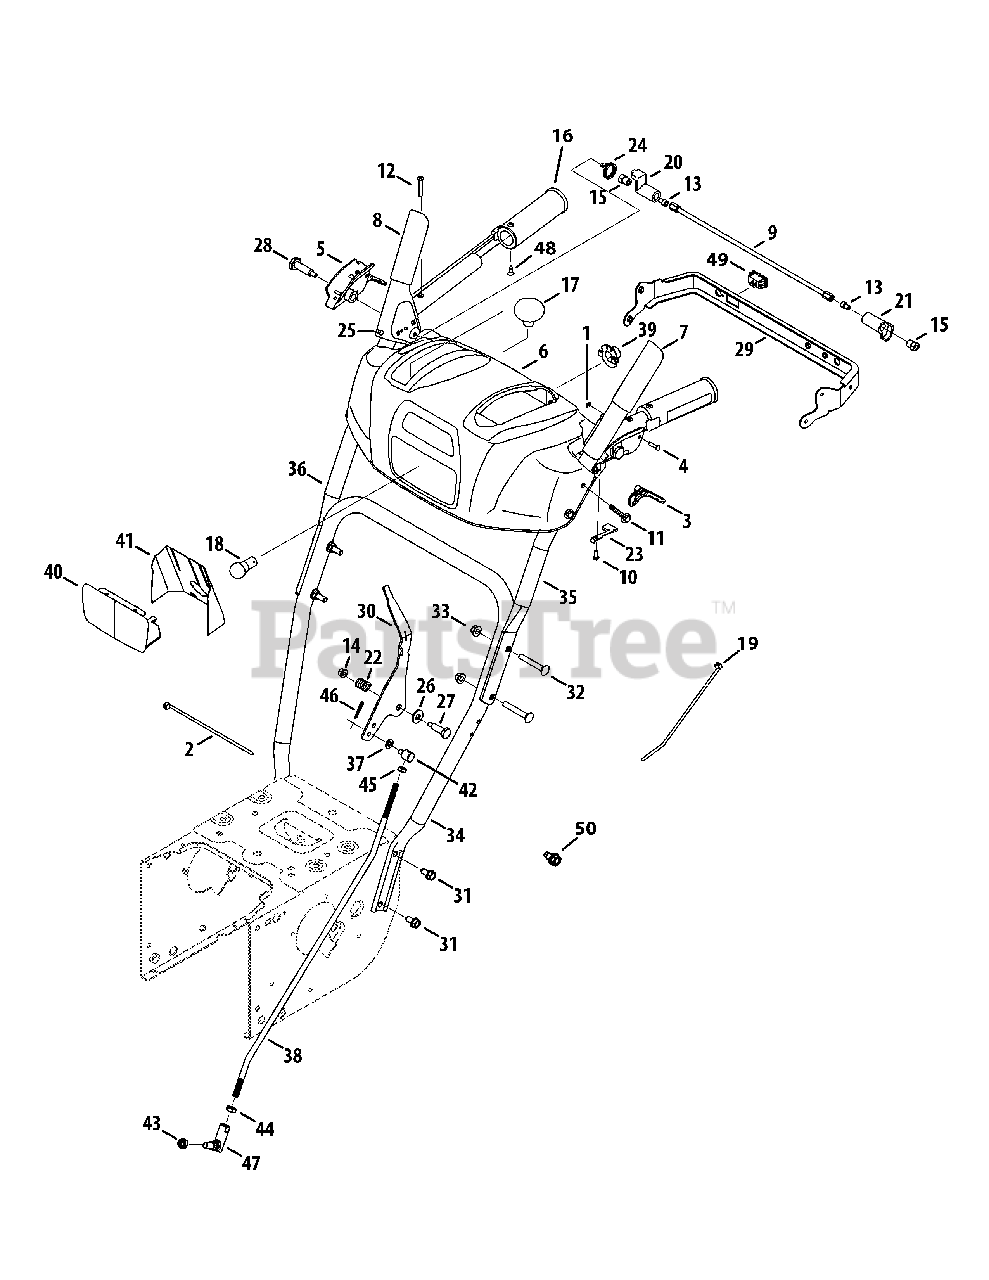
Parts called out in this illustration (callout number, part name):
2	Cable Tie
3	Clutch Trigger
5	Handle Clutch Lock LH Assy
5	Handle Clutch Lock RH Assy
6	Handle Panel, includes Ref. 40 & 41
7	Handle Engagement Assembly LH
8	Handle Engagement Assembly RH
10	Screw, 8-16 x 0.50
11	Screw, 1/4-20 x 1.625
12	Screw, 10-24 x 1.375
13	Socket Screw, 1/4-20 x .50
14	Flange Lock Nut, 1/4-20
15	Shoulder Nut, 1/4-20
16	Heated Grip
17	Shift Knob
19	Cable Tie
21	Clutch Lock Cam
22	Compression Spring
23	Clutch Lock Spring
24	Torsion Spring
25	Rubber Bumper
26	Flat Washer, .385 x .87 x .06
27	Shoulder Screw, .374 x 1.05
28	Shoulder Screw, 1/4-20 x 1.345
29	Panel Bracket
31	Hex Screw, 5/16-18 x .750
32	Carriage Screw, 5/16-18 x 2.00
33	Nut, Flangelock, 5/16-18
34	Lower Handle
35	Upper Handle LH
36	Upper Handle RH
37	Flat Washer, .320 x .600 x .060
38	Shift Rod, .343 OD
39	Light Socket
41	Lens Label
42	Ferrule, 5/16-18 x .312 Dia
43	Jam Lock Nut, 3/8-24
44	Jam Nut, 3/8-24
45	Nut, Jam 5/16-18
46	Bow-Tie Cotter Pin
47	Ball Joint
48	AB Screw, #10-16 x .625
49	Heated Grip Switch
50	Screw, TT, 1/4-20 x .500 (For ground wire)
